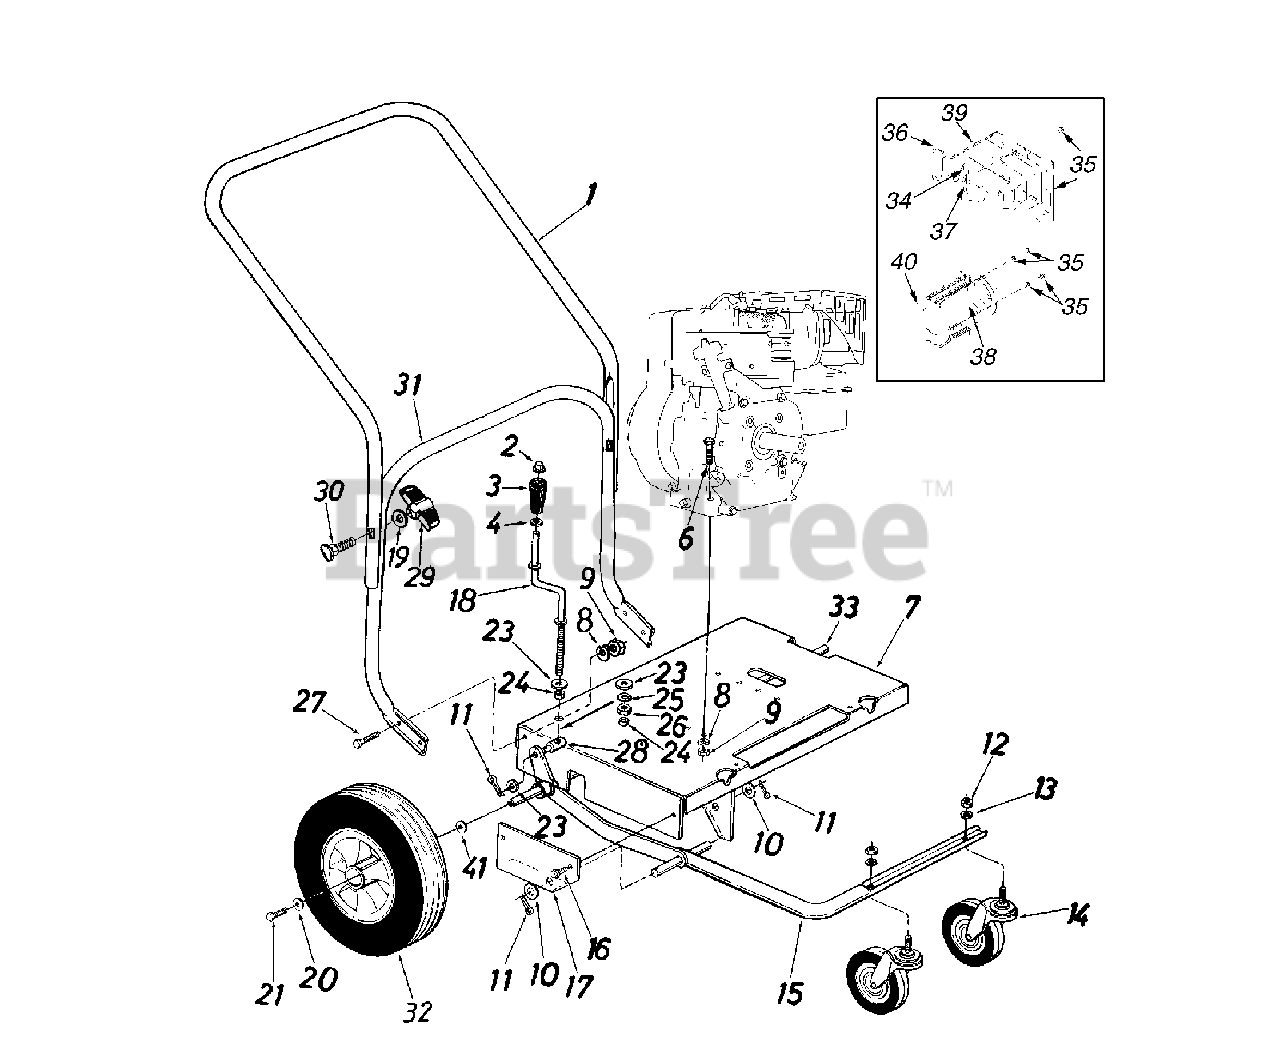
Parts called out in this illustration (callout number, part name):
2	Push Nut 3/8" Rod
3	Crank Knob
4	Fl-Wash. .385" I.D. x .62"
6	Hex Bolt 5/16-18 x 1.50" Lg. (Gr. 5)
9	Hex Nut 5/16-18 Thd.
10	Fl-Wash. .63" I.D. x 1.25"
11	Cotter Pin 1/8" Dia. x 1.0"
12	Hex Nut 1/2-13 Thd.
13	L-Wash. 1/2" I.D.
14	Swivel Caster Wheel 5" Dia. x 1.25"
19	Saddle Wash. .32" I.D. x .93"
20	Fl-Wash. .34" I.D. x .87" O.D.
21	Hex L-Bolt 5/16-24 x .64" Lg.
23	Fl-Wash. .38" I.D. x .57"
24	Spacer .382" I.D. x .50" x .180" Lg.
25	L-Wash. 3/8" I.D.
26	Hex Nut 3/8-8 Thd.
27	Hex Bolt 5/16-18 x .75" Lg. (Gr. 5)
28	Ferrule
29	Hand Knob
30	Carriage Bolt 5/16-18 x 2.0"
33	Rear Axle
34	Scr. TT. 1/4-20: .5"
35	Scr. AB 8-18:.375
36	Nut-Lock Hx. Flg. 5/16-18
37	Lockwasher
38	Deflector
39	Guard - Muffler
40	Bracket - Muffler Guard
41	Flat Washer
